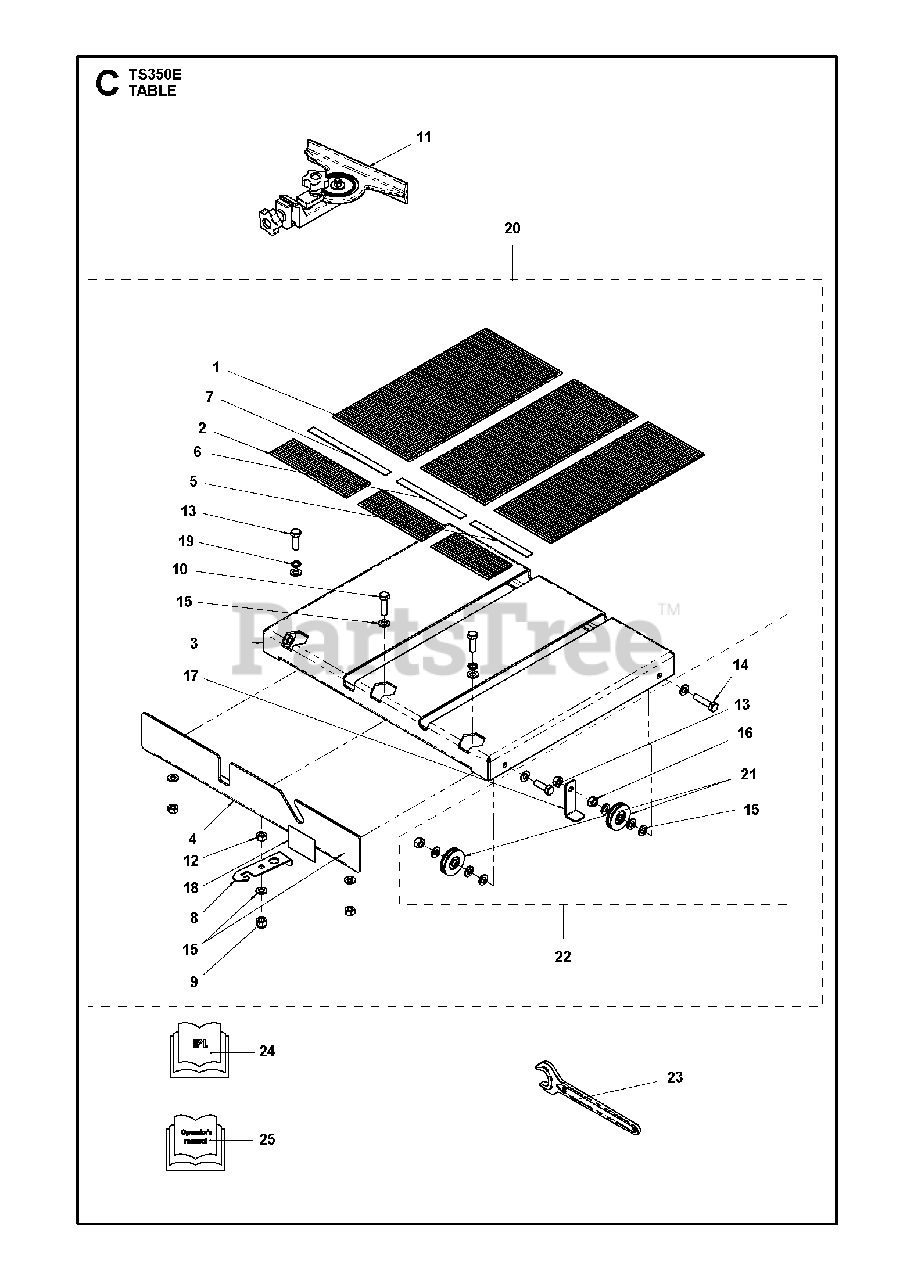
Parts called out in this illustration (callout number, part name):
1	TAPIS AR STRIE ADHESIF/
2	TAPIS AV STRIE ADHESIF/TS400F
5	RULER, RIGHT TS350E-02TS350E-0
6	RULER, MIDDLE TS350E-02TS350E-
7	RULER, LEFT TS350E-02TS350E-02
9	HEXAGON LOCKING NUT
12	HEXAGON NUT
15	WASHER
16	HEXAGON NUT
17	RETENUE DE TABLE/TS 350 F
24	ILLUSTRATED PARTS LIST
